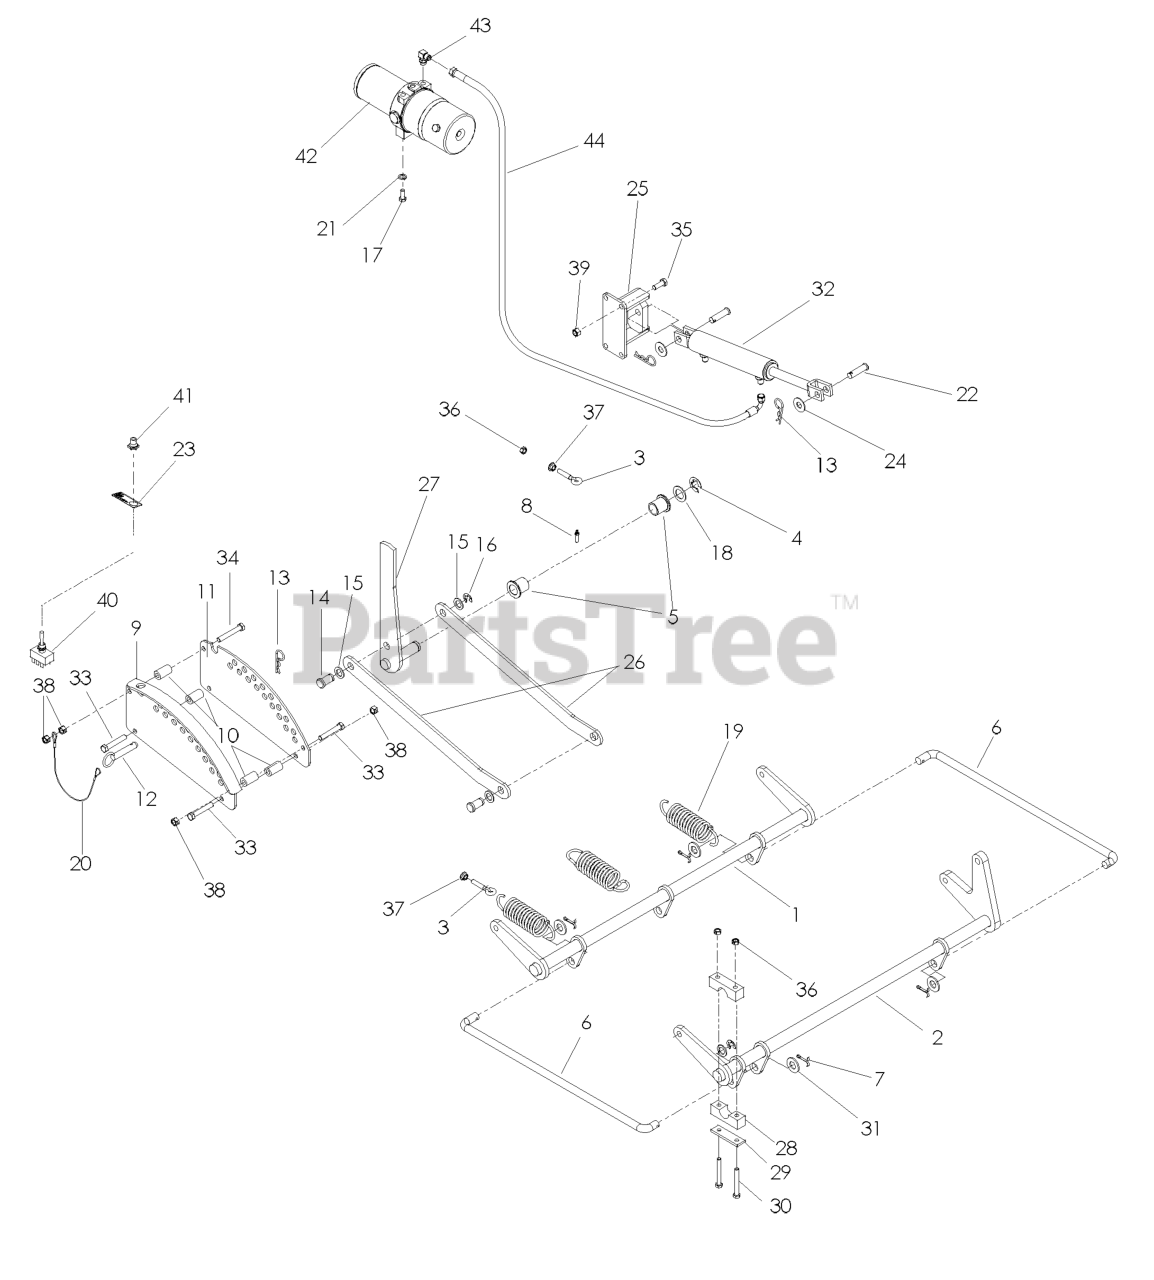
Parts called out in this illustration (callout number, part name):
1	SHAFT LIFT REAR
2	LIFT SHAFT WELDMT FRONT
3	EYEBOLT, RH
4	E-RING 7/8
5	BUSHING, FLANGED
6	CONNECTING LINK
7	GREASE ZERK LONG
8	COTTER PIN
9	ADJ. PLATE WLDMNT
10	DECK LIFT SPACER
11	ADJ. PLATE PAINTED
13	HAIRPIN #4
14	CLEVIS PIN
15	BUSHING
16	E-RING 5/8
17	SCREW 3/8C X 3/4 HEX CAP
18	BSHG .875 X 1.375 X .074 ZD
19	DECK LIFT SPRING
21	SLW 3/8 STD
22	CLEVIS PIN 1/2 X 3/4
23	DECAL, LIFT SWITCH
24	WASHER 1/2 FLAT
25	CYLINDER MTG WLDMT
26	LIFT LINKAGE,PAINTED
27	LIFT LEVER
28	PILLOW BLOCK
29	REINFORCEMENT BAR
30	BOLT 5/16C X 2 1/2
31	WASHER 5/8 FLAT
32	HYDRAULIC CYLINDER
33	HCS 3/8C X 2 1/4
34	HCS 3/8C X 2 1/2
35	HCS 3/8-16X1.GRD.5.ZD
36	NUT 5/16C CENTERLOCK
37	NUT 5/16C WHIZ
38	NUT 3/8C CENTERBLOCK
39	NUT 3/8-16 NYLOC
41	SWITCH BOOT
42	HYDRAULIC POWER UNIT
